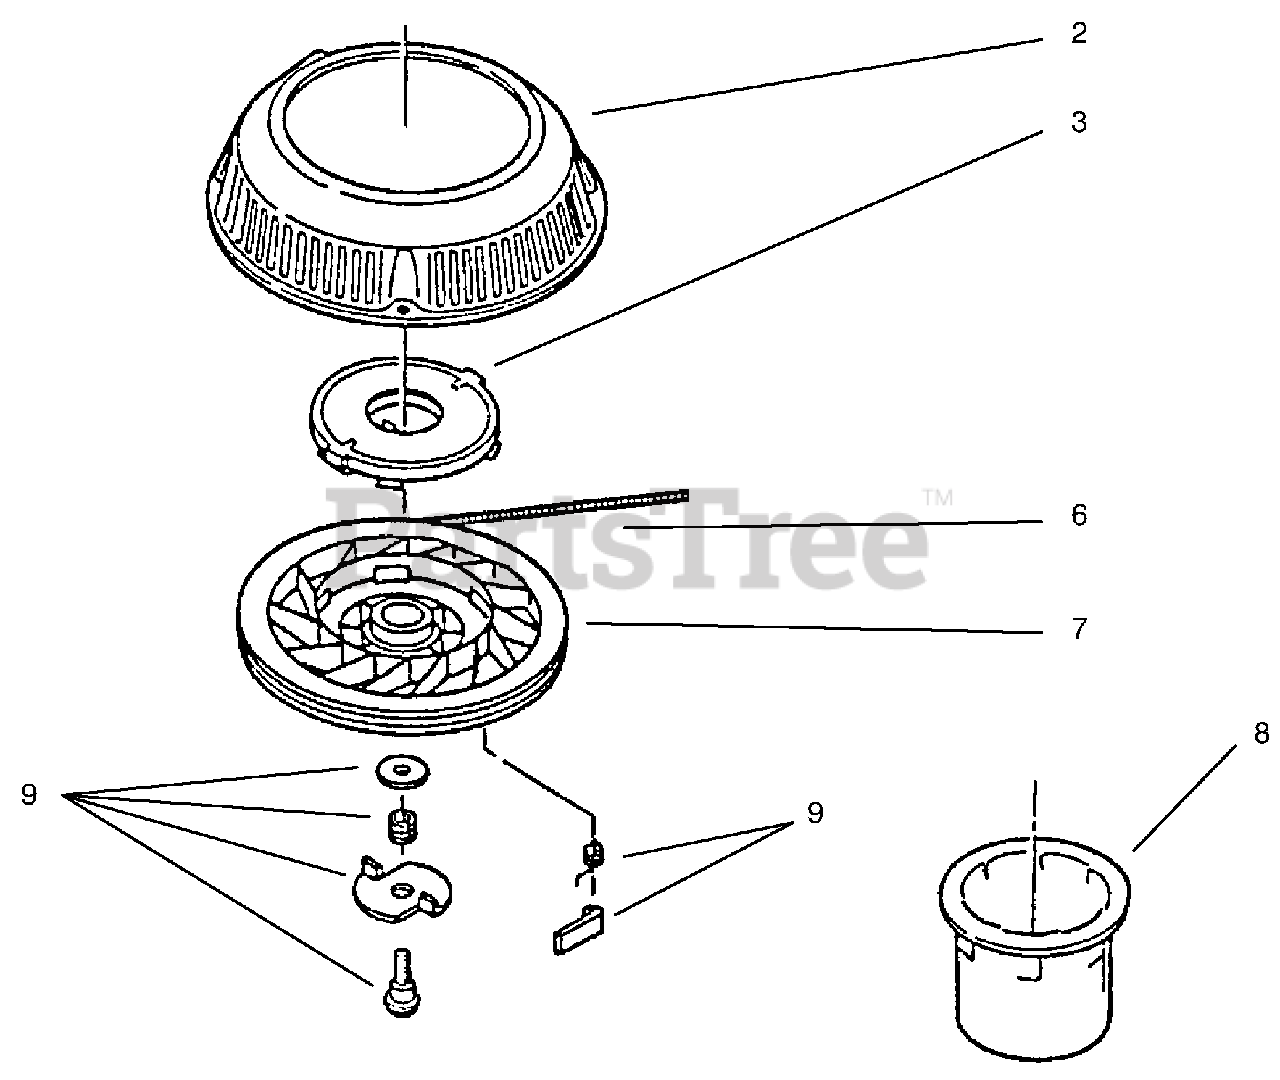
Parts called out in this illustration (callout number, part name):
2	Starter Housing & Shaft
3	Spring & Keeper
6	Rope
8	Hub-Starter
9	Kit-Dog
